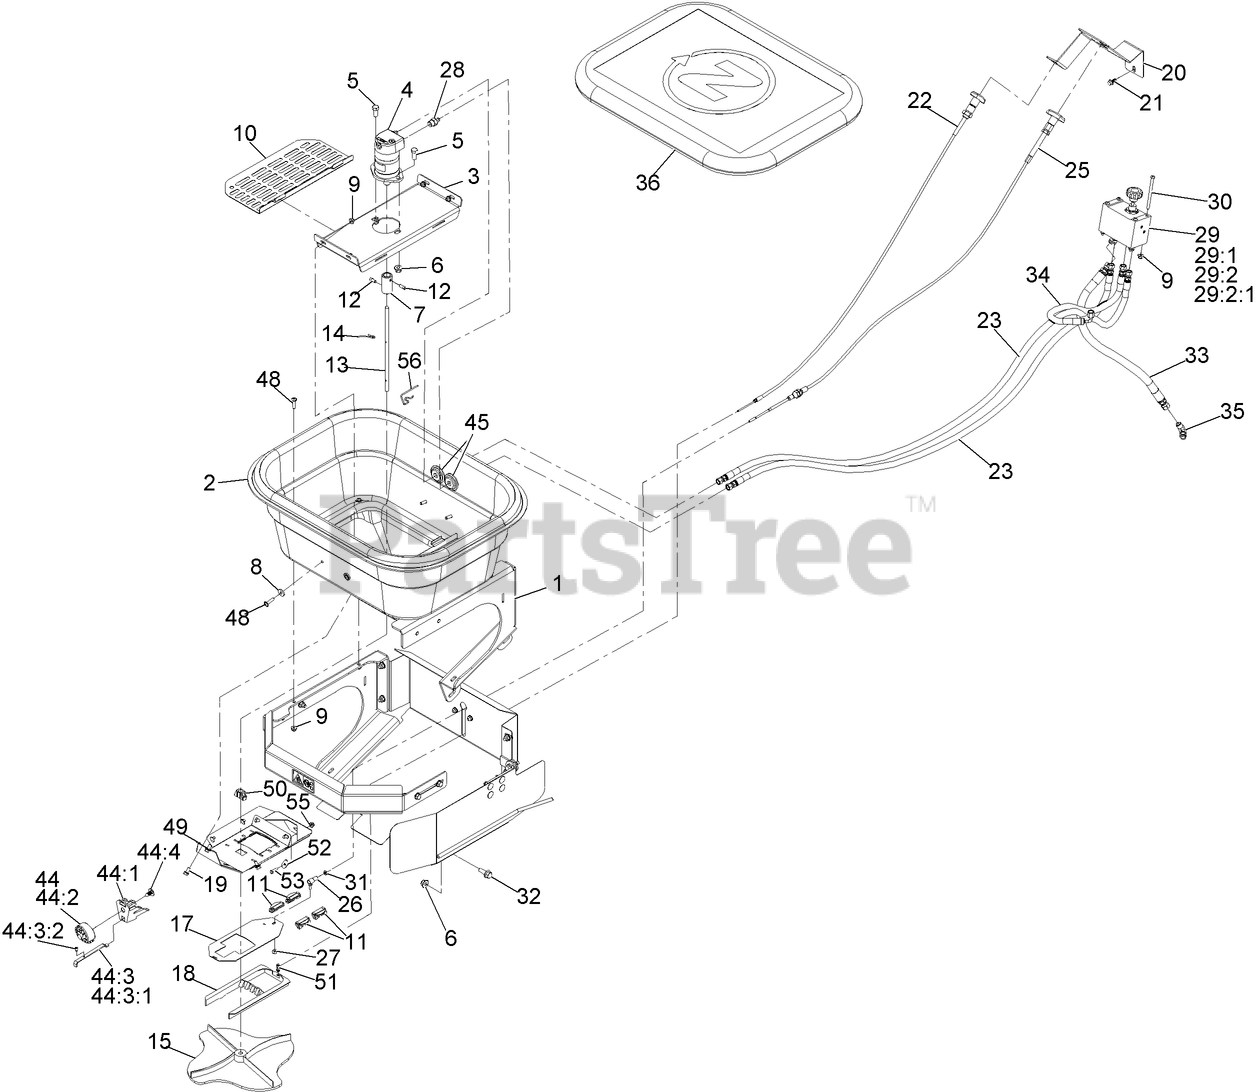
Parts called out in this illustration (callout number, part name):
1	Hopper ASM
2	HOPPER-120LB
3	PAN, HOPPER, 120
4	MOTOR-HYDRAULIC, SPREADER
5	SCREW-HH
6	Nut-Hex Flange
7	COUPLER-SS
9	Nut-Hex Flange
10	SCREEN, HOPPER, 120
11	GUIDE-RATE, GATE
12	Screw-SQH
13	SHAFT-HOPPER, 120
14	WIRE-AGITATOR
15	Spinner-Spreader
17	SLIDE-DOOR, HOPPER
18	DIFFUSER
19	SCREW-HHF
20	Bracket-Hopper Cable
21	Screw-HHF 1/4-20 X 5/8
22	CABLE-PUSH/PULL
23	HOSE ASM-HYD HP
25	CABLE-PUSH/PULL
26	BALL JOINT-SS
27	Nut,NYL Lock,#10-32,ST/ST 18-8
29	Manifold-Flow Control, Hopper
29:2	FITTING-ELBOW, 45 DEG
29:2:1	O-RING
30	Screw-HSBH
31	Nut,Hex Jam Mch Scr,10-32,Sst
32	SCREW-HHF
33	HOSE ASM-HYD HP
34	HOSE ASM
35	FITTING-90 SWIVEL
36	COVER-HOPPER, SMALL
44	RATE DIAL ASM
44:1	MOUNT-DIAL
44:3	Rate Gate Link ASM
44:3:1	LINK-GATE, RATE
44:3:2	SCREW-SHOULDER, SLOTTED
44:4	Footpad Fastener
45	Grommet-Hopper
48	Screw-Hsbhf
49	BASE PLATE, HOPPER, 120
50	HOPPER BOTTOM BEARING
51	WIRE-STOP
52	RETAINER, CABLE
53	SCREW-HH
55	Nut-Hex Flange
56	Clip-Spinner
